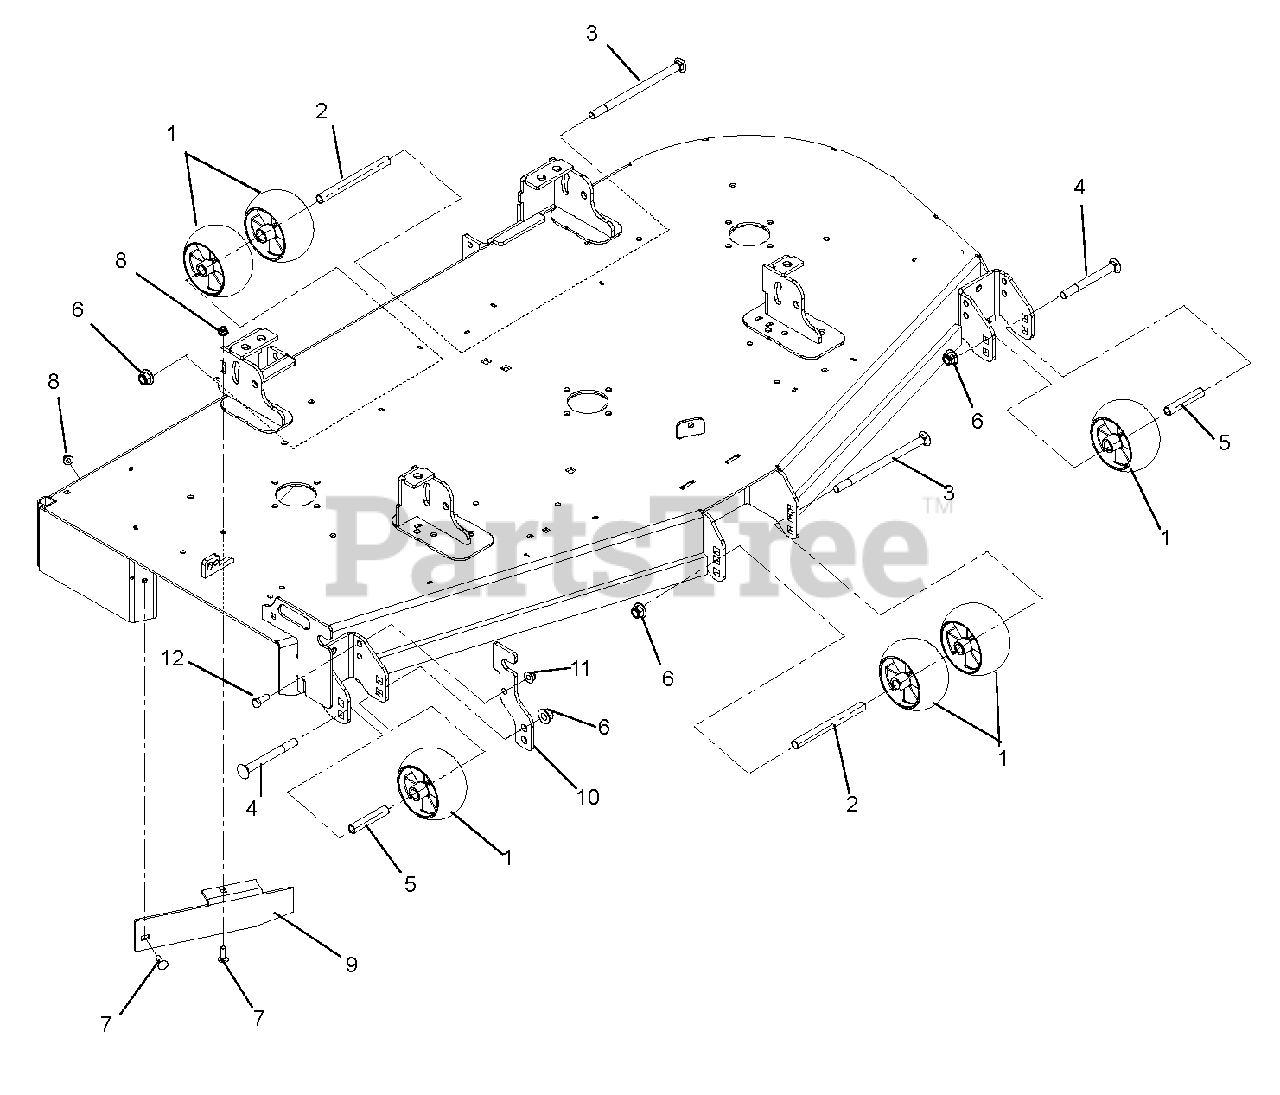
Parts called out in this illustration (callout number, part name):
1	Anti-Scalp Wheel- 5 x 3 Center
2	Spacer, .510 x .625 x 6.70
3	Bolt, Round Head Square Neck .50-13 x 8.50
4	Bolt, Round Head Square Neck .50-13 x 5.00
5	Spacer, .510 x .625 x 3.35
6	Nut, Locking-Nylon-Flange .50-13
7	Bolt, Round Head Square Neck .31-18 x 1.00 Grade 5
8	Nut, Locking-Nylon-Flange .31-18
9	60" Discharge Baffle (185, 187)
10	Bracket, Chute Storage
11	Nut, Locking-Nylon-Flange .38-16
12	Bolt, Hex .38-16 x 1.00 Grade 5
